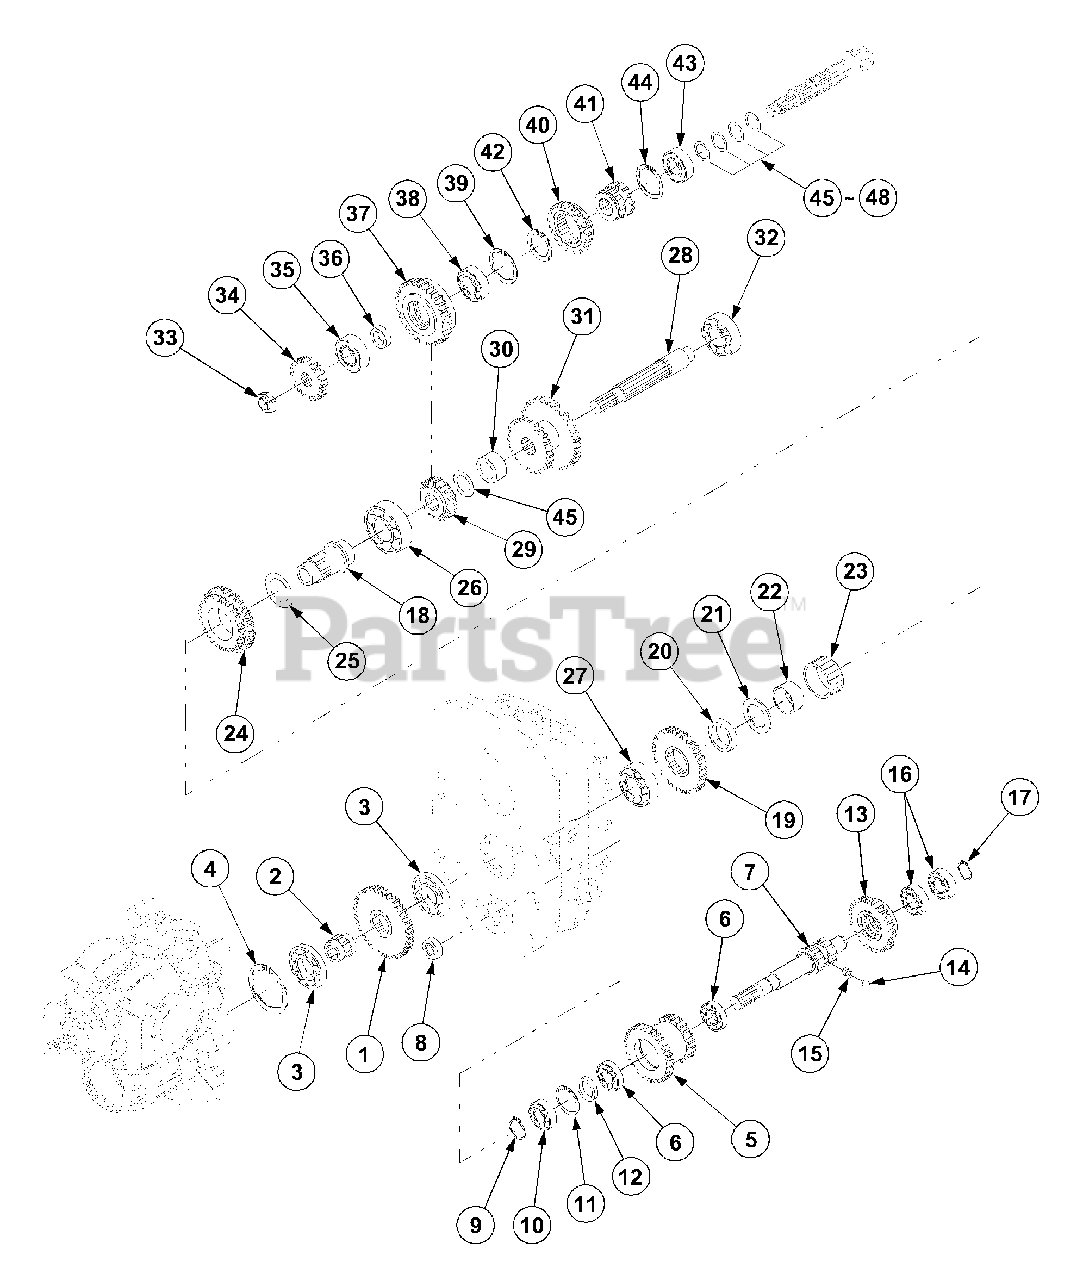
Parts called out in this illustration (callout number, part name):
11	C-Ring
23	Bearing,Needle
35	Bearing,Taper
39	C-Ring
42	C-Ring
43	Bearing,Taper
44	C-Ring
